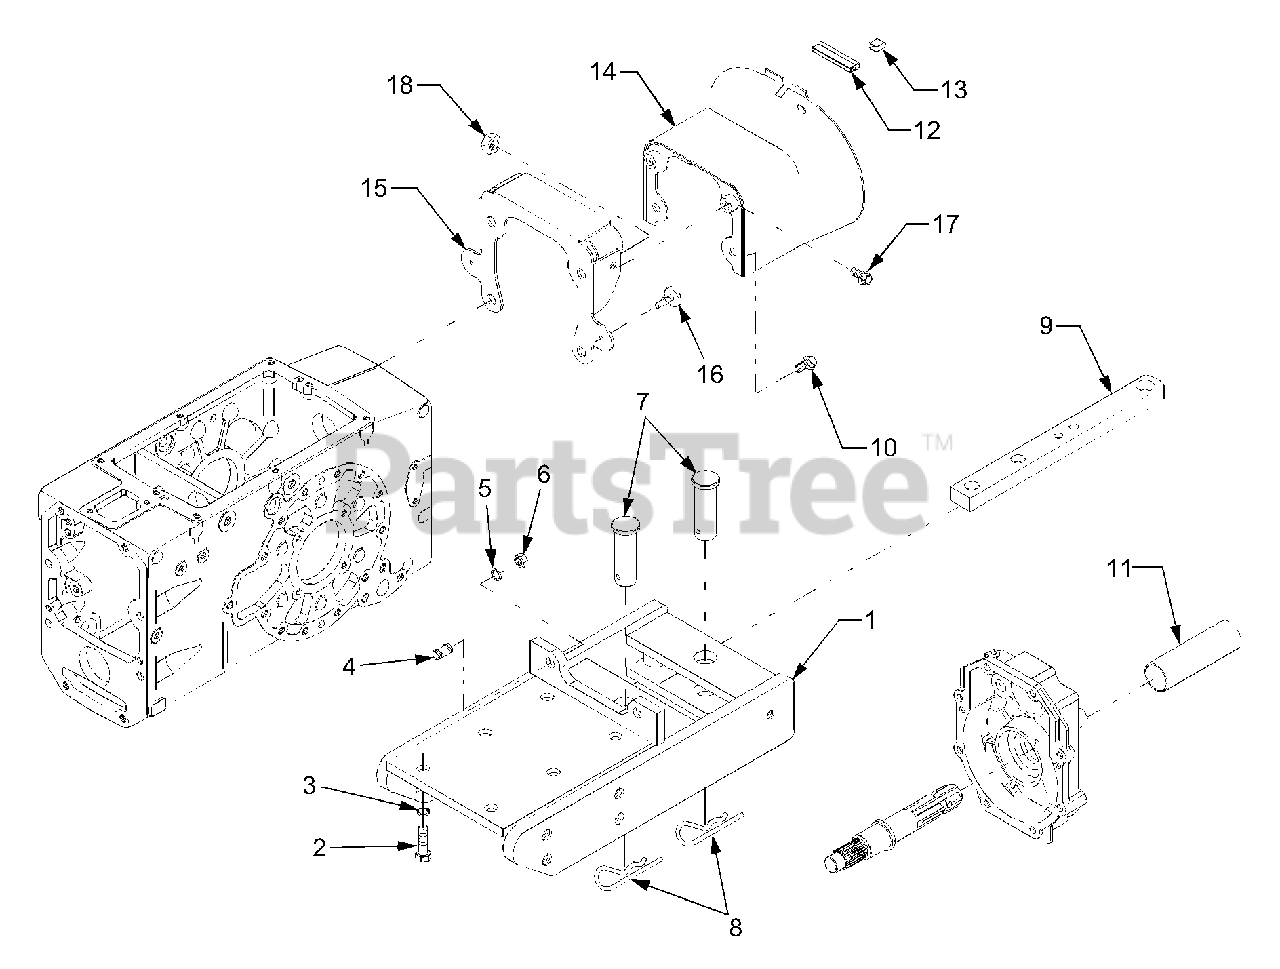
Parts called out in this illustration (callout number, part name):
1	Frame, Swinging Drawbar
3	Washer, Spring
5	Washer, Spring
9	Drawbar
11	Cover, PTO Shaft
12	Boot (PTO Cover)
15	Plate, PTO Cover
